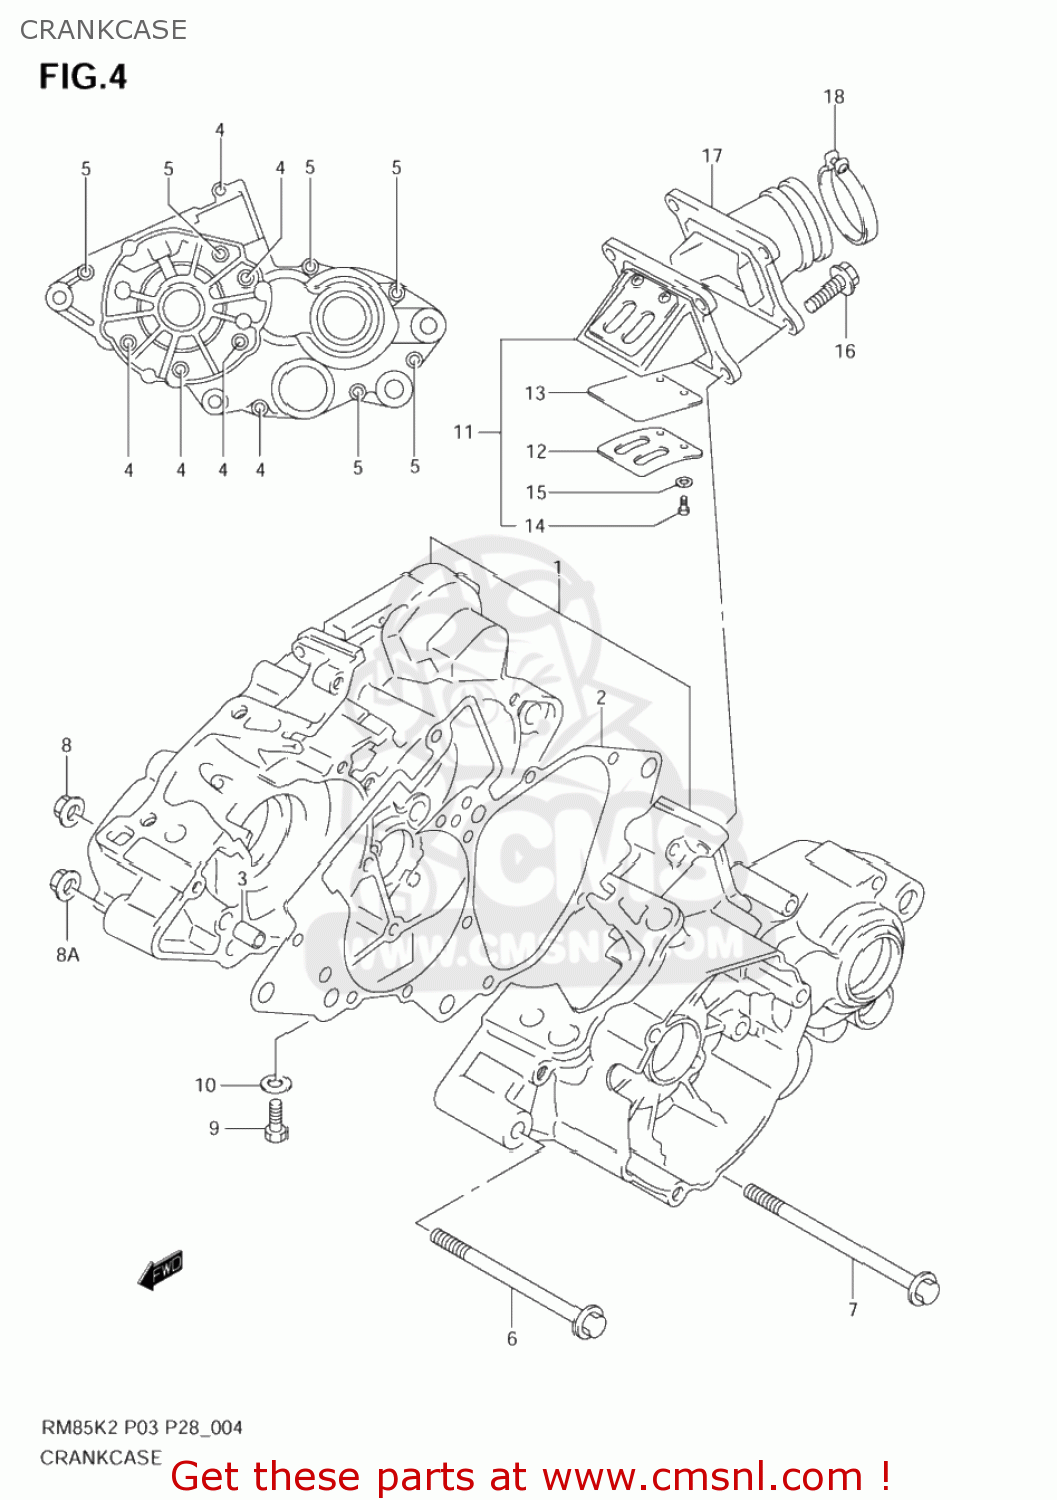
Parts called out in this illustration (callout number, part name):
1	CRANKCASE SET
2	GASKET,CRANKCA (NAS)
3	PIN
4	BOLT(6X40)
5	BOLT(6X50)
6	BOLT(10X95)
7	BOLT(8X102)
8	NUT
8A	NUT
9	BOLT
10	GASKET(8.2X14X1) (NAS)
11	VALVE ASSY,REED
12	STOPPER,REED VALVE
13	VALVE,REED
14	SCREW
15	WASHER,LOCK
16	BOLT,6X20
17	PIPE,INTAKE
18	CLAMP
